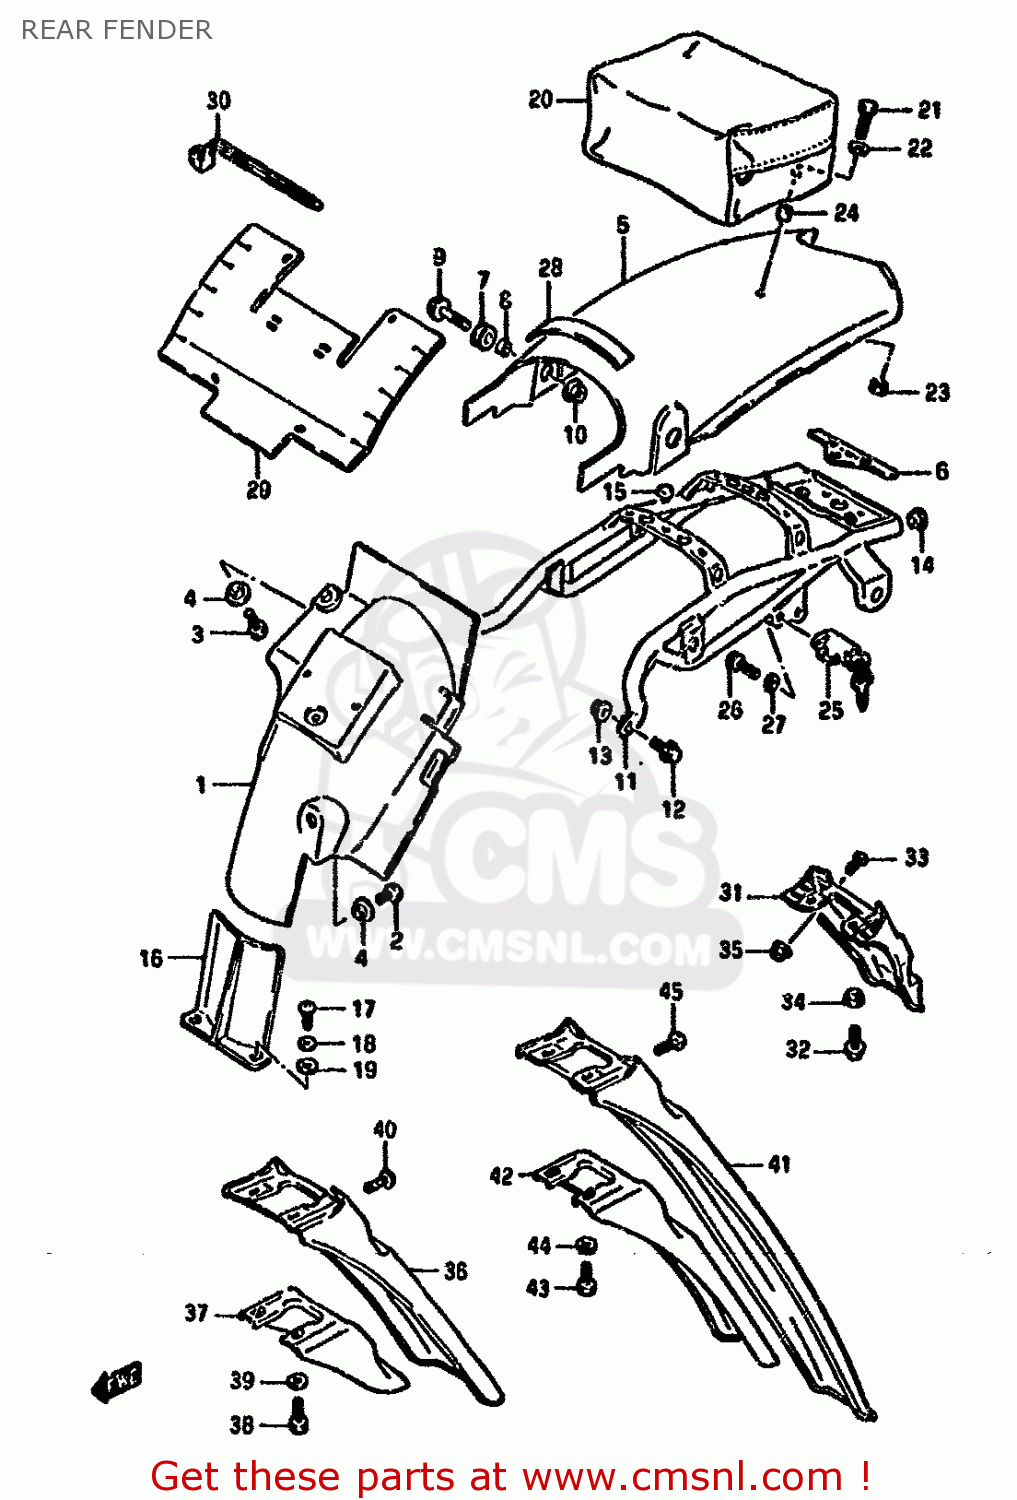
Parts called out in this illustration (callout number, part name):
1	FENDER,REAR
2	BOLT
3	BOLT 6X16
4	WASHER
5	BODY,REAR FENDER REAR (BLUE)
6	CUSHION,RR FENDER
7	CUSHION
8	SPACER (8.2X12X7.5)
9	BOLT
10	NUT
11	REINFORCEMENT
12	BOLT
13	NUT
14	PLUG
15	CUSHION
16	GUARD,RR UNIT MUD
17	SCREW
18	WASHER(6.5X16X1.2)
19	WASHER,LOCK
20	BAG ASSEMBLY,SEAT TAIL
21	BOLT
22	WASHER
23	NUT
24	SPACER (6.1X9X9)
25	LOCK ASSEMBLY,HELMET
26	BOLT 6X11
27	WASHER,LOCK
28	CUSHION(25X185X15)
29	FLAP,AIR CLEANER MUD
30	CLAMP(L:125)
31	EXTENSION,RR FENDER
32	BOLT
33	SCREW
34	WASHER
35	NUT
36	EXTENSION
37	REINFORCEMENT
38	BOLT
39	WASHER
40	SCREW
41	EXTENSION
42	REINFORCEMENT
43	BOLT
44	WASHER
45	SCREW
